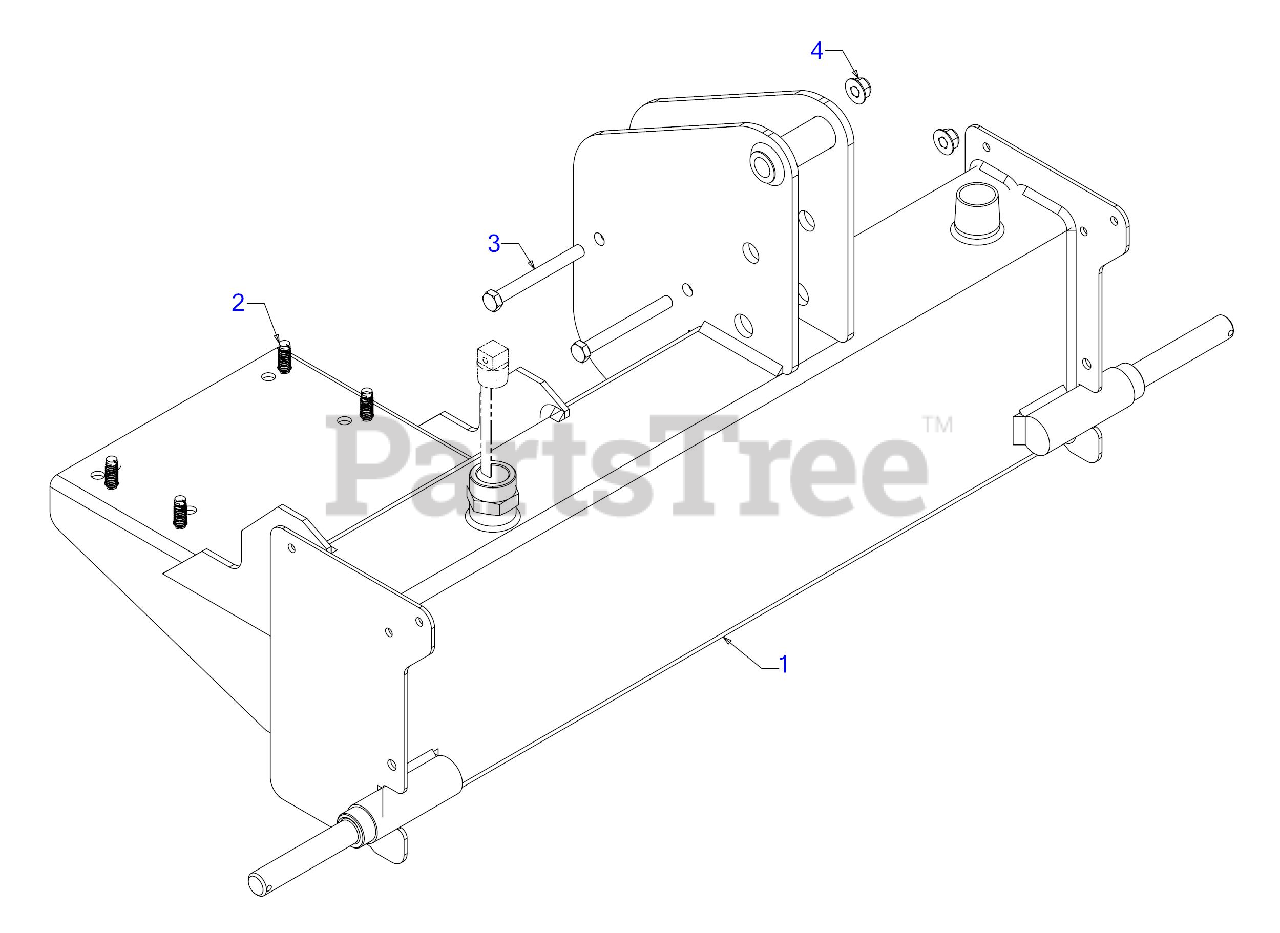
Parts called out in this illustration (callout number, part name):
1	TANK ASSEMBLY
2	SCREW 3/8-16 x 1
3	SCREW 3/8-16 x 3.50 GR5
